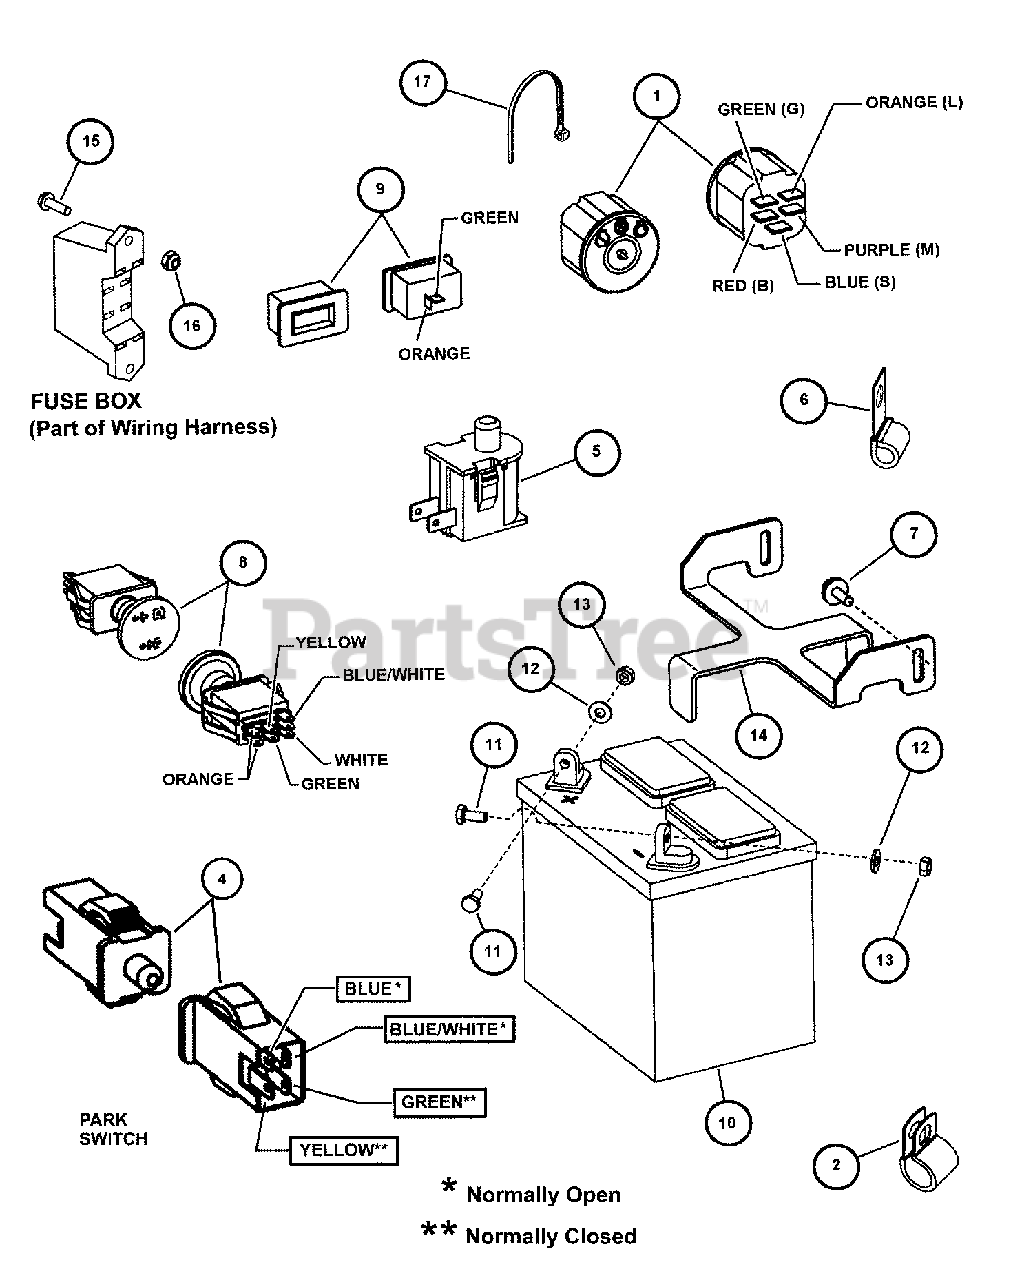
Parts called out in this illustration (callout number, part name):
1	SWITCH, Ignition
2	CLIP, Harness
4	SWITCH, DP NO/NC SNAP-IN
5	SWITCH, Seat, NC
6	CLIP, Open J 3/8 Cushioned
7	SCREW, 1/4-20 x 5/8" Hex Head w/loose captured washer
8	SWITCH, PTO, Yellow
9	HOUR METER w/2 Flash Alerts
10	BATTERY, 12V - Wet, 11 Plate 375CCA
11	SCREW, 1/4-20 x 5/8" Hex Head Cap, GR 5
12	WASHER, 9/32 I.D. x 5/8" O.D. Flat
13	NUT, 1/4-20 Hex Center Lock, GR 5 or B
14	BRACKET, Battery Hold-Down
15	SCREW, #10-32 x 5/8" Hex Washer Self-Tap
16	NUT, #10-32 Hex Nyloc
17	CABLE TIE, 7" long
